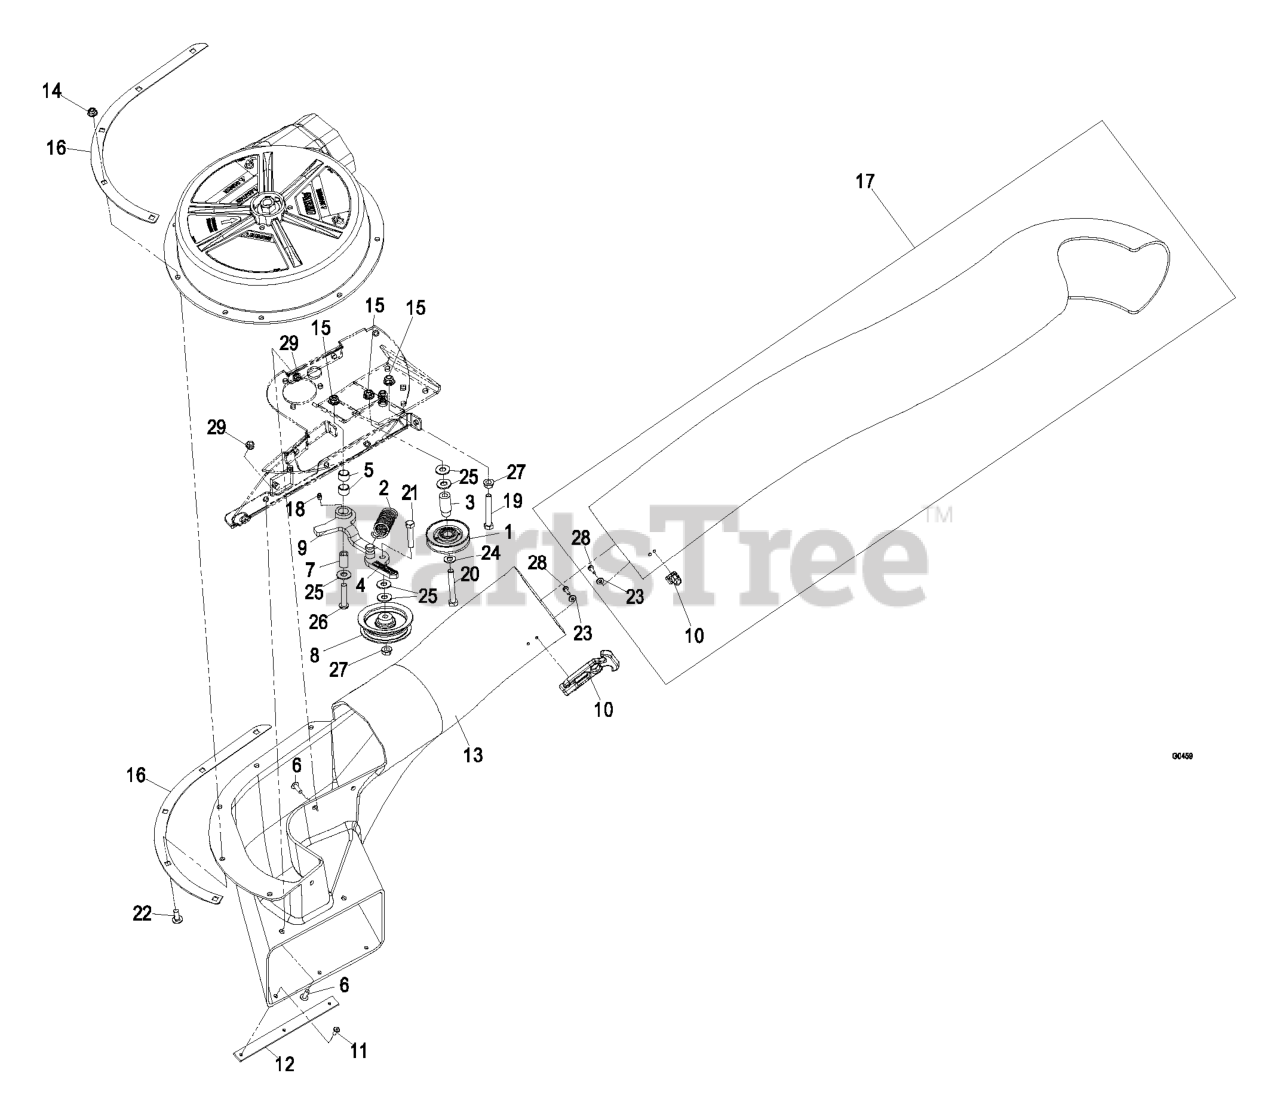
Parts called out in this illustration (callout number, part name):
1	IDLER-INSIDE
2	SPRING-IDLER
4	DECAL-WARNING
5	BUSHING
7	BUSHING-PIVOT, IDLER
8	IDLER-FLAT
9	Asm, Idler W/Decal & Bushings
10	LATCH DRAW
11	RIVET-BLIND
12	PLATE-REINFORCEMENT
14	NUT-HF, NI
15	NUT-HF, NI
16	BKT,COVER REINFORCEMENT
17	UPPER TUBE ASM
18	FITTING-GREASE
19	BOLT-CARR
20	SCREW-HH
21	SCREW-HH
22	BOLT-CARR
23	WASHER-FLAT
24	WASHER-FLAT
25	WASHER-FLAT
26	SCREW-HSBH
27	NUT-HHF, WHIZ
28	SCREW-PPH
